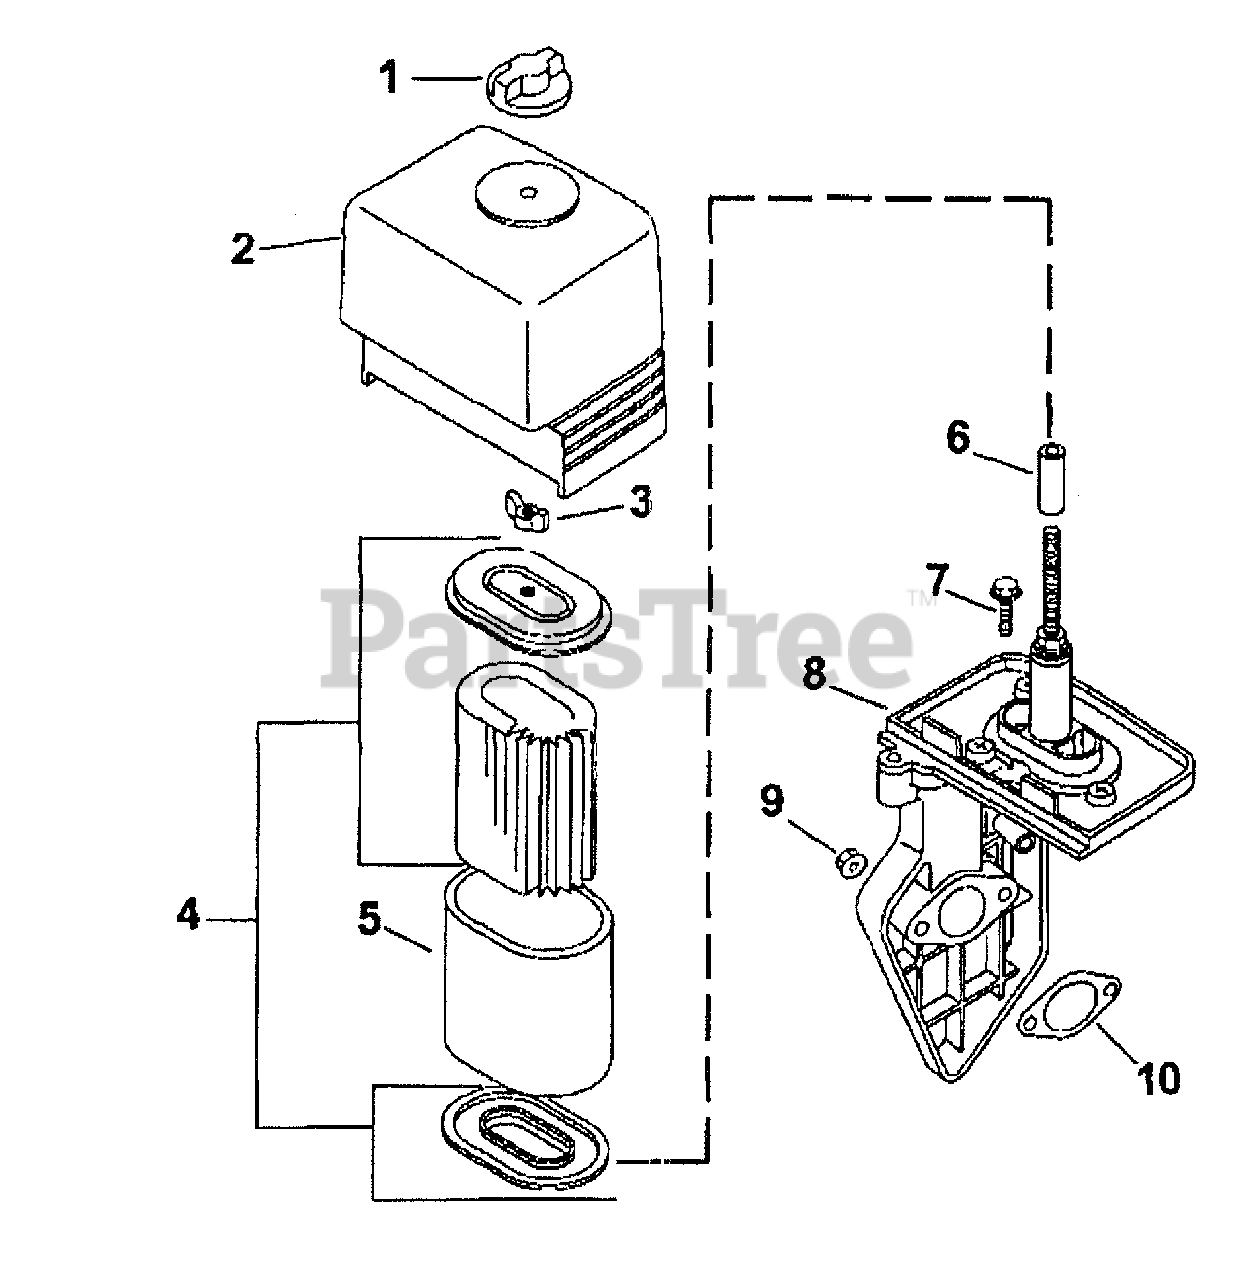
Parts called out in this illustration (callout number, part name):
1	Nut, Air Cleaner
2	Cover, Air Cleaner
3	Nut, Wing-Air Cleaner
4	Element, Air Cleaner
5	Element, Precleaner
6	Seal, Air Cleaner
8	Base, Air Cleaner
9	Nut, Air Cleaner
10	Gasket, Air Cleaner
